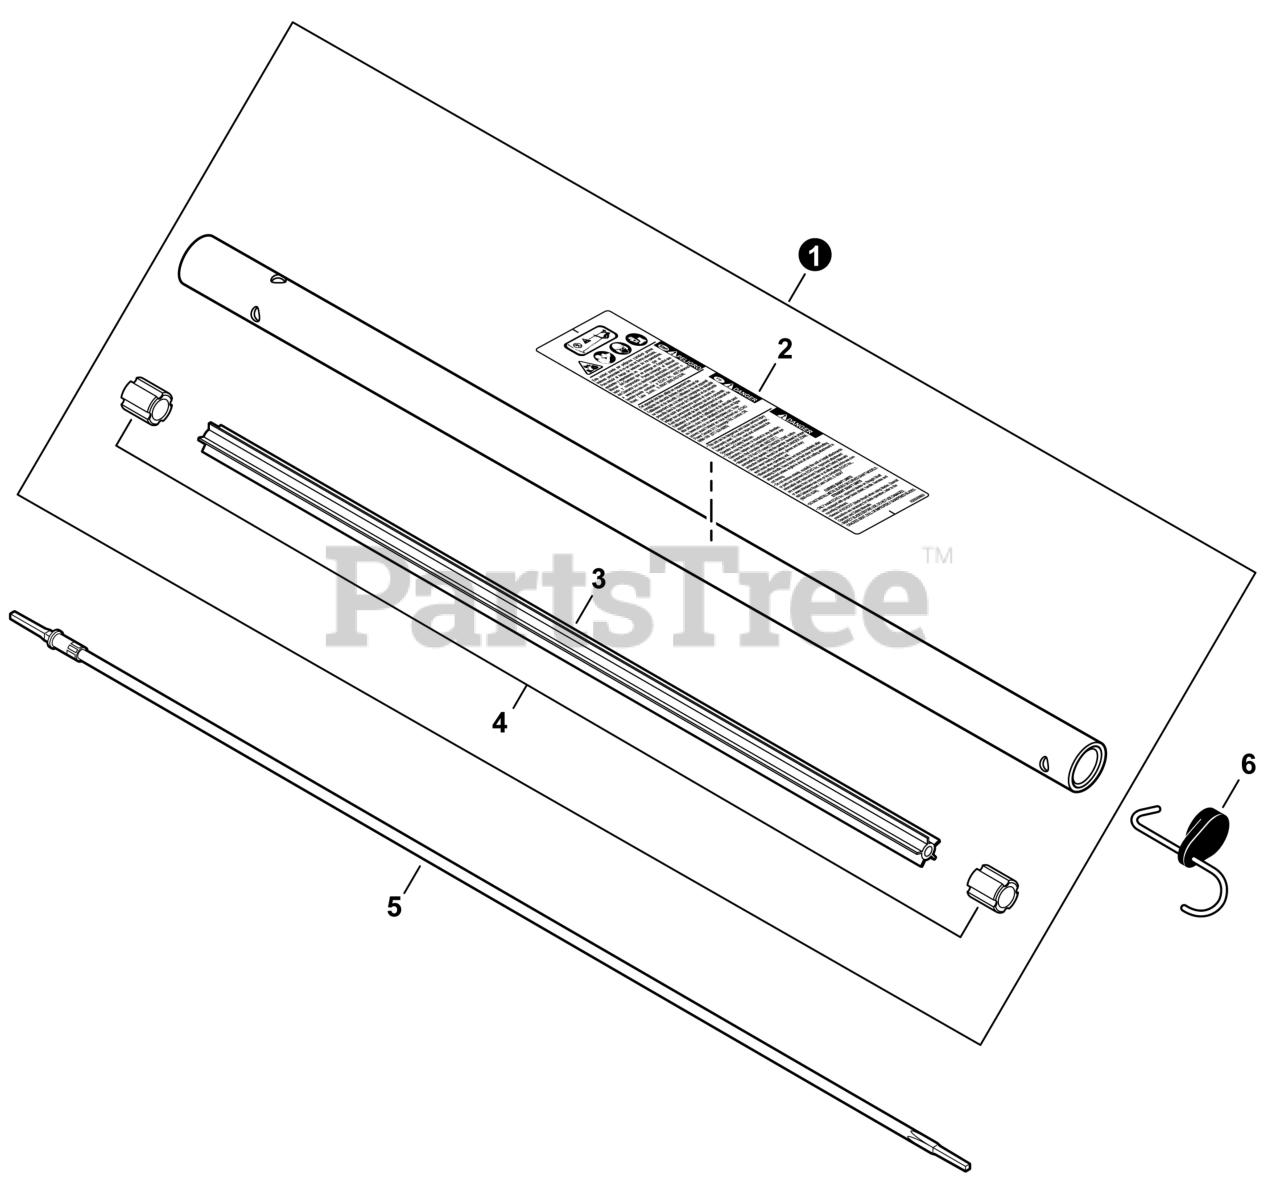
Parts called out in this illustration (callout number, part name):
1	MAIN PIPE ASSY
2	LABEL - CAUTION
3	LINER - FLEXIBLE
5	DRIVESHAFT - FLEXIBLE
6	HANGER, ATTACHMENT
